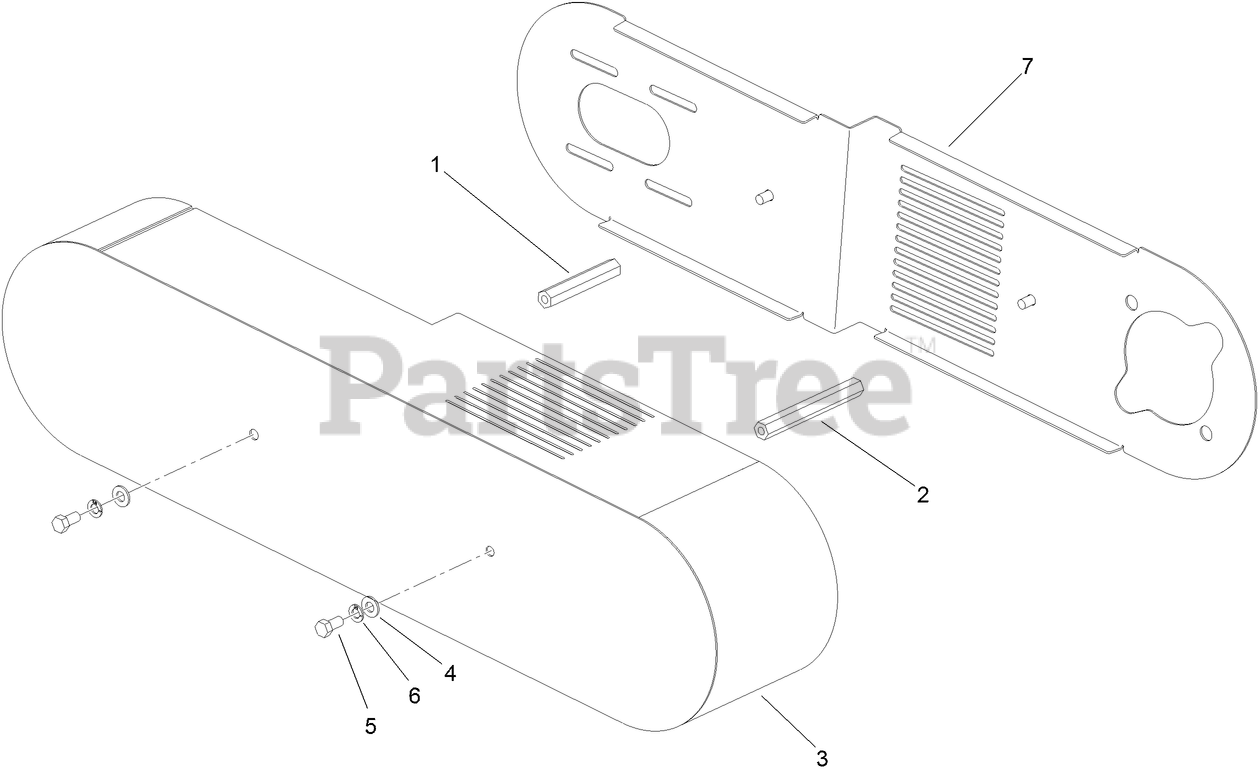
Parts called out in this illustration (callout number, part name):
1	TUBE-STANDOFF, SHORT
2	TUBE-STANDOFF, LONG
3	BELT GUARD COVER ASM
4	WASHER-FLAT
5	SCREW-HH
6	WASHER-LOCK
7	GUARD-BELT, INNER
